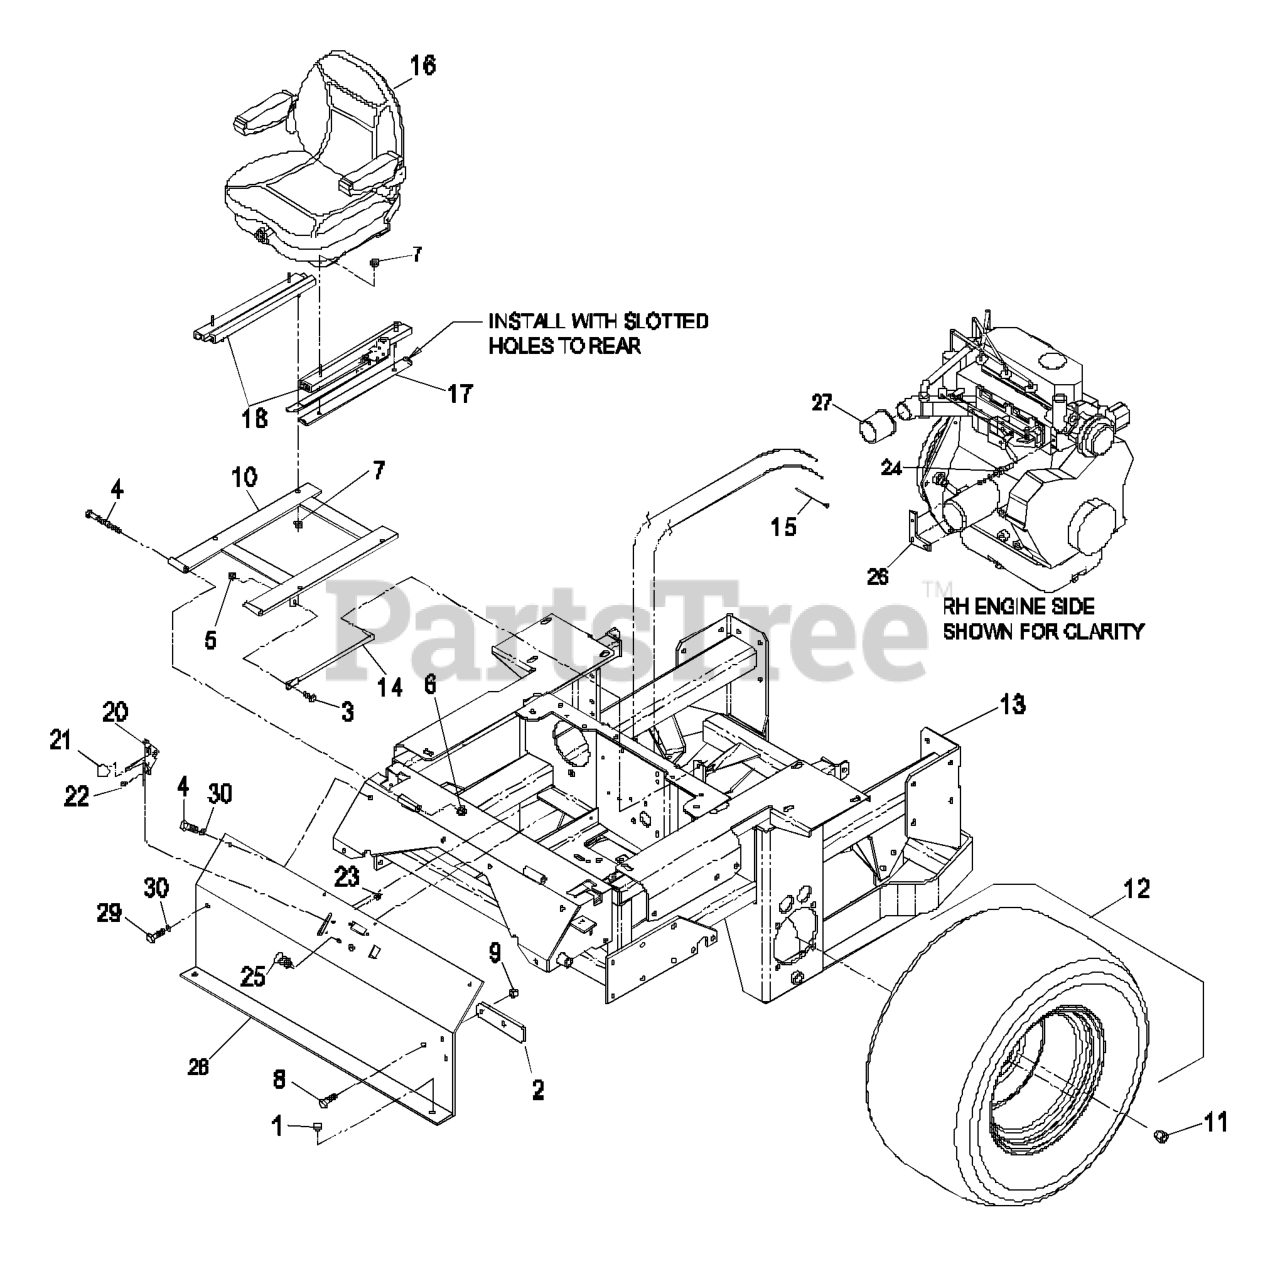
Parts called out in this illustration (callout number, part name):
2	STOP-BRAKE, PARK
3	SCREW-HH
4	SCREW-HH
5	NUT-LOCK, NI
6	NUT-LOCK, NI
8	SCREW-HH
9	NUT-HHF, WHIZ
11	NUT-LUG
14	ROD,HOLDUP SEAT
15	TIE-PLASTIC
16	Seat, Suspension
17	STOP-SEAT
18	TRACK-SEAT
20	CABLE-THROTTLE
21	KNOB-BALL
22	BOLT-CARR
23	NUT-LOCK, NI
24	SENDER-TEMPERATURE
25	CABLE,CHOKE
27	BUSHING,1.75/2.00 RUBBER
28	PANEL,CONSOLE XP
29	SCREW-HH
30	WASHER-PLAIN
